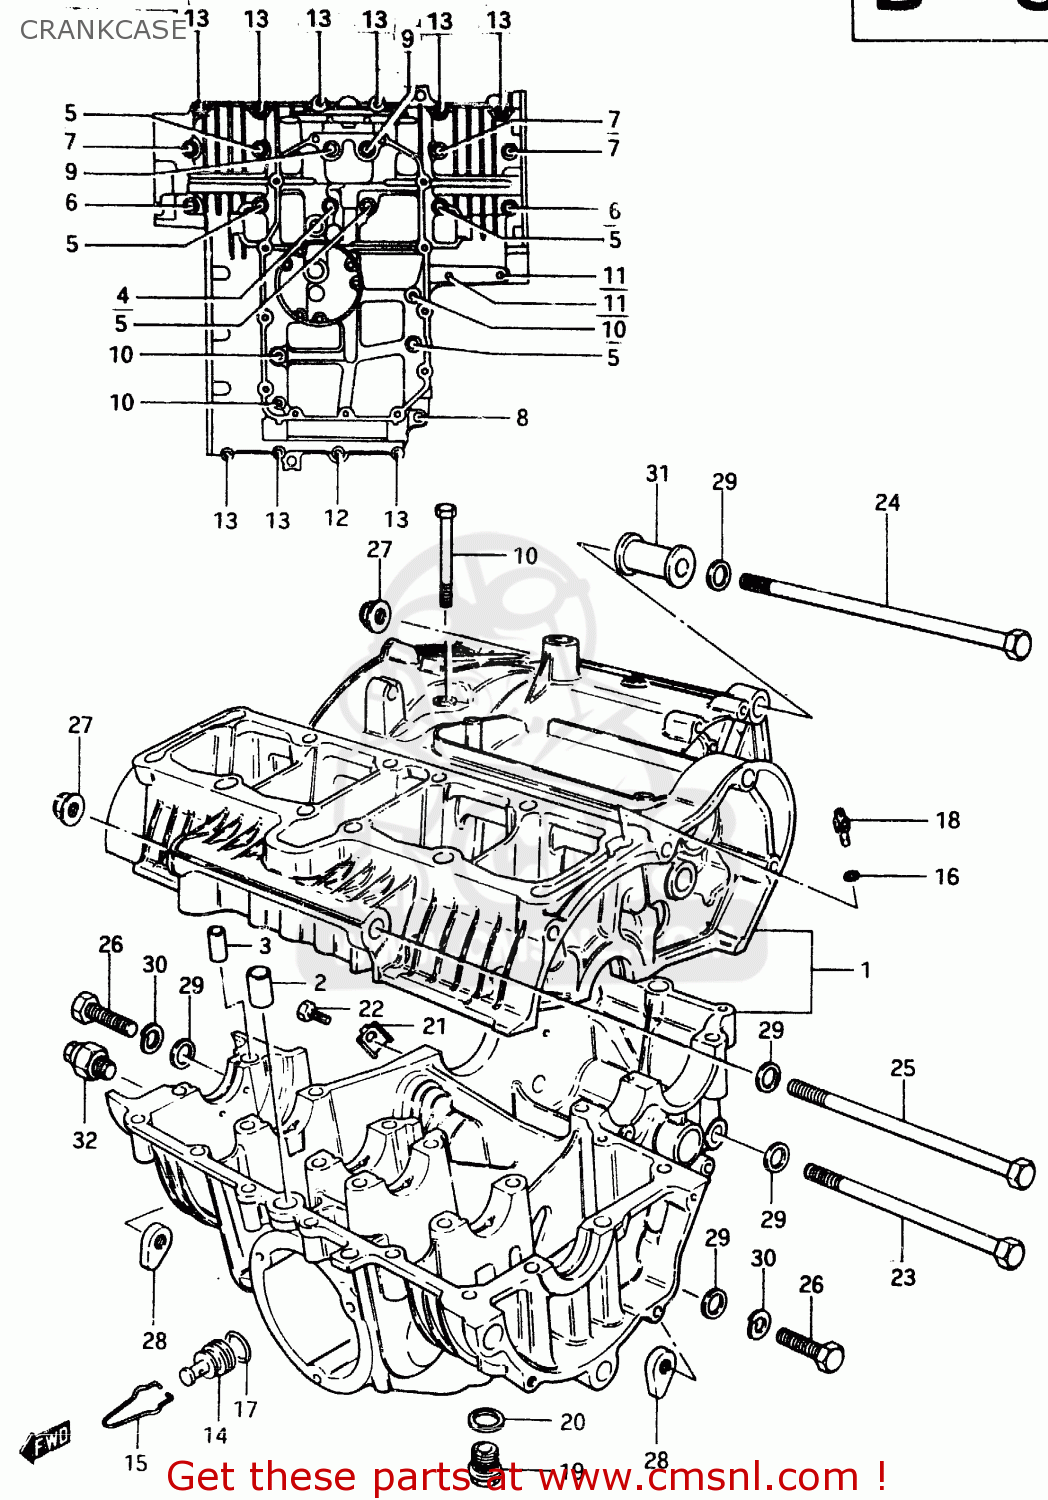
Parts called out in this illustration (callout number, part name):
1	CRANKCASE SET
2	PIN(10.4X13X22)
3	PIN (11X20)(SUS)
4	BOLT
5	BOLT
6	BOLT
7	BOLT 8X85
8	BOLT 8X60
9	BOLT
10	BOLT
11	BOLT (6X75)
12	BOLT 6X55
13	BOLT (6X40)
14	JET, OIL GALLERY CYLINDER
15	CLIP
16	O-RING,OIL GALLERY JET
17	O RING(D:1.9,ID:11)
18	JET,AIR(14)
19	PLUG
20	GASKET(16X22X2) (NAS)
21	PLATE
22	BOLT
23	BOLT
24	BOLT 10X230
25	BOLT(10X180)
26	BOLT
27	NUT 10MM
28	NUT
29	WASHER
30	LOCK WASHER
31	SPACER,ENGINE MOUNT
32	SWITCH ASSEMBLY
